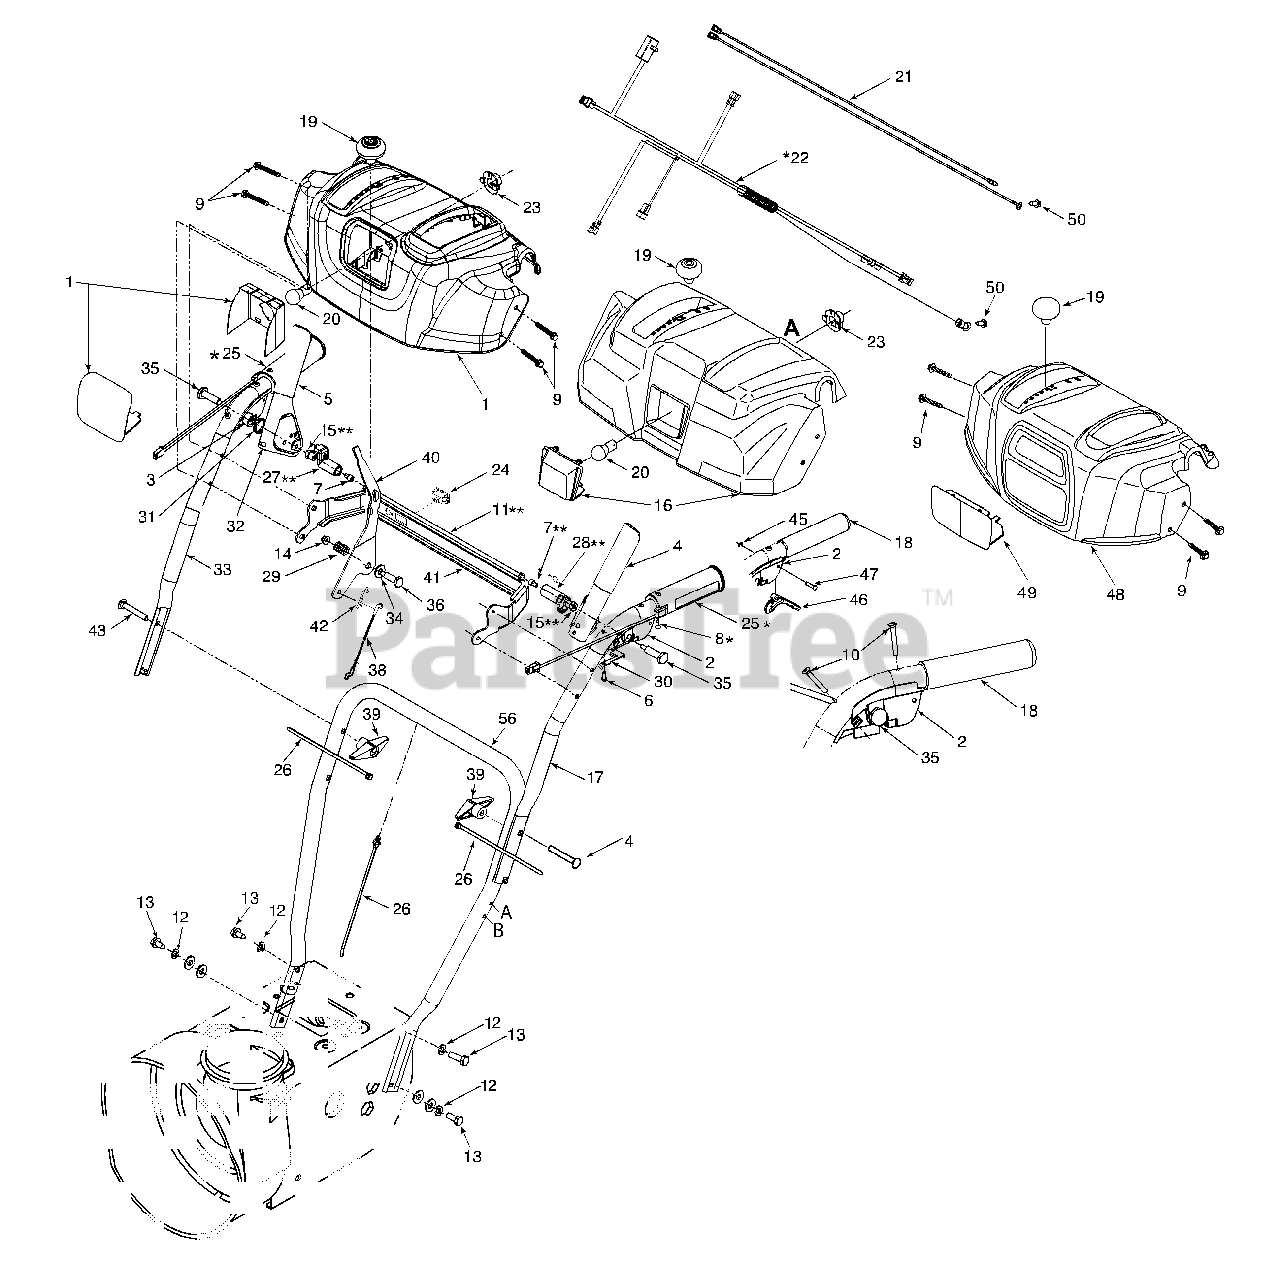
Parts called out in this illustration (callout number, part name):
1	Handle Panel Ass’y - Yellow
1	Handle Panel Ass’y - Black
1	Handle Panel Ass’y-Black w/Chute Control
1	Handle Panel Ass’y-Grey w/Chute Control
2	LH Clutch Lock Handle Ass’y
3	RH Clutch Lock Handle Ass’y
4	Engagement Handle Assembly LH - Black
4	Engagement Handle Assembly LH - Red
5	Engagement Handle Assembly RH - Black
5	Engagement Handle Assembly RH - Red
6	Screw #8-16 x .50
7	Hex Cap Socket Screw 1/4-20 x .5
8	Oval HD C-Sunk Scr #10 x 5/8
9	Hex TT-Tap Scr 1/4-20 x 1.625
10	Oval C-Sunk Hd Screw 10-24 x 1.375
11	Pivot Rod
12	Lockwasher 5/16 ID
13	Hex TT Screw 5/16-18 x .75 Gr. 5 Patch
14	Hex L-Flanged Nut 1/4-20 Gr. F Nylon
15	Hex Shoulder Nut 1/4-20
15	Hex L-Flg Nut 1/4-20 Gr. F Nylon
16	Handle Panel Ass’y - Troy-Bilt
17	Upper Handle LH - Powder Black
19	Shift Knob
19	Shift Knob - Yellow
20	Lamp (179 cc/208 cc engines)
20	Lamp (277 cc/347 cc & 420 cc engines)
21	Wire Harness
22	Wire Harness Heated Grip
23	Socket
24	Switch
25	Heated Grip
26	Cable Tie (w/plug)
26	Cable Tie (w/heated grips)
27	Lock Plate
28	Clutch Lock Cam
29	Compression Spring .38 ID x .88 Lg
30	Spring: Clutch Lock
31	Torsion Spring .8156 x .3038
32	Rubber Bumper
33	Upper Handle RH - Powder Black
34	Flat Washer .38 ID x .87 OD x .09
35	Shoulder Screw .437 x 1.345: 1/4-20
36	Shoulder Screw .374 Dia. x 1.05 Lg.
37	Flat Washer .344 ID x .688 OD x .065
38	Selector Speed Cable
39	Handle Knob Assembly
41	Panel Support
42	Cotter Pin
43	Carriage Bolt 5/16-18 x 2.25
44	Lower Handle - Powder Black
45	E Ring
46	Steering Control - Black
46	Steering Control - Yellow
47	Pin 3/16
48	Handle Panel Ass’y - Red (w/lens)
50	Hex Wash S-Tapp Scr 1/4-20 x .50
